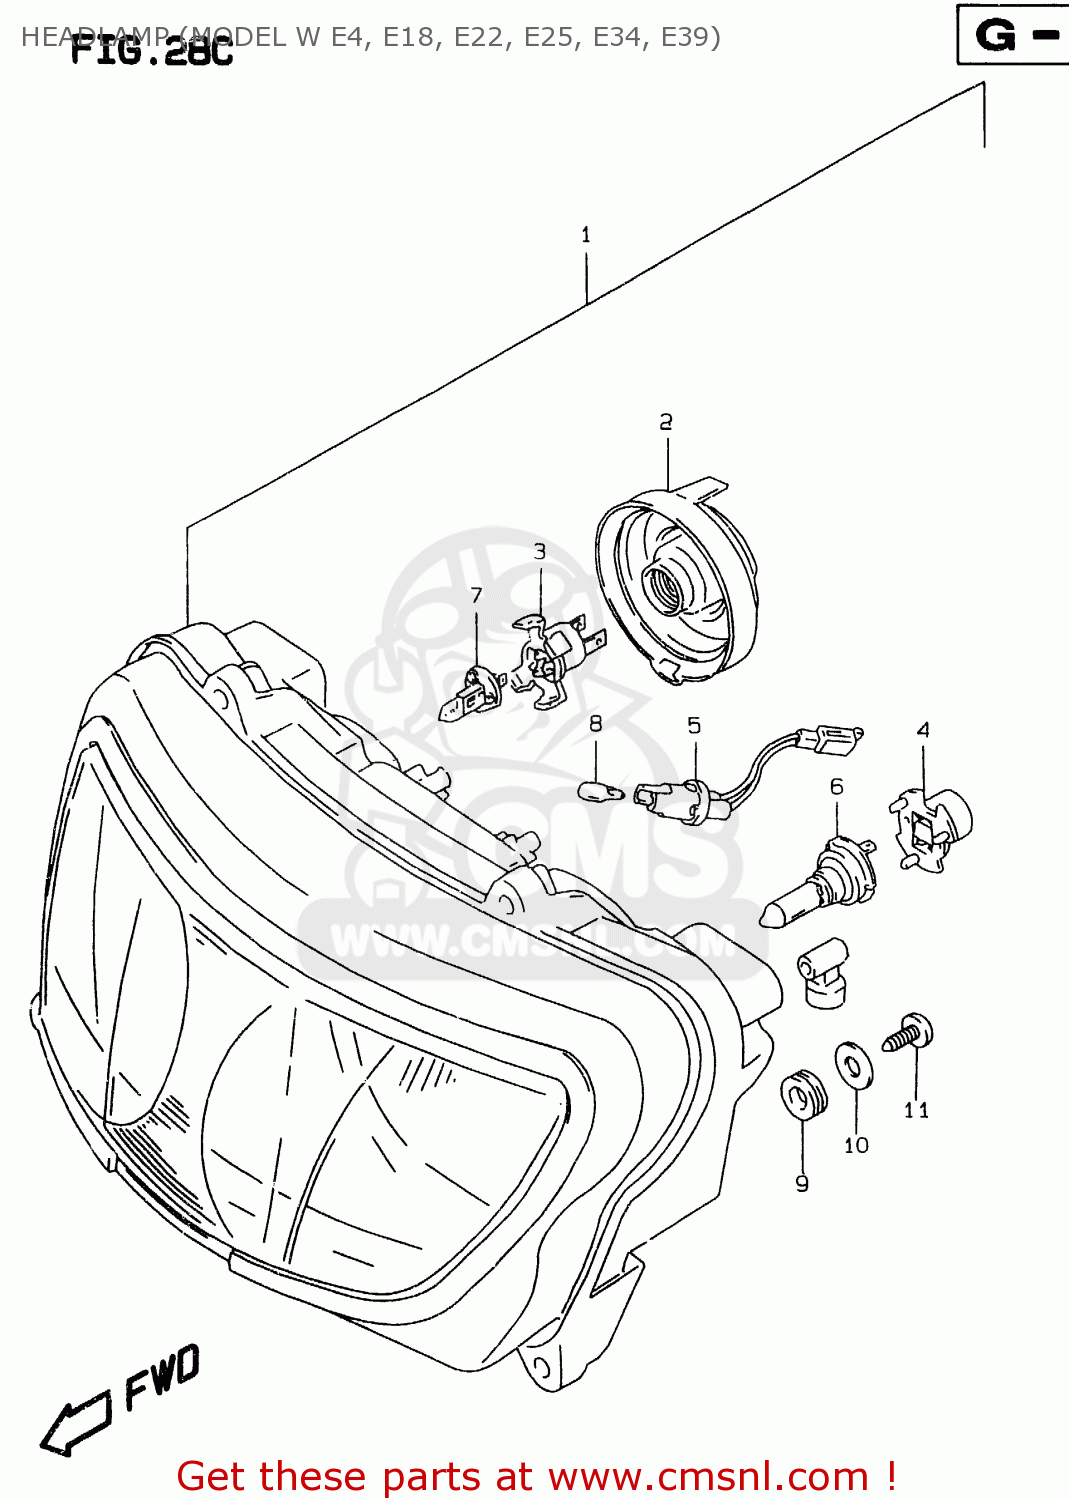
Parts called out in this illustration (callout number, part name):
1	HEADLAMP ASSY
2	COVER,SOCKET
3	ADAPTER ASSY
4	ADAPTER ASSY
5	SOCKET ASSY
6	BULB(12V55W/H7/PX26D/PHILIPS)
7	BULB(12V55W/H1/P14.5S/OSRA,PHI
8	BULB(12V5W)
9	CUSHION,HEADLAMP
10	WASHER(5.5X18X1)
11	SCREW,SIDE HOL
